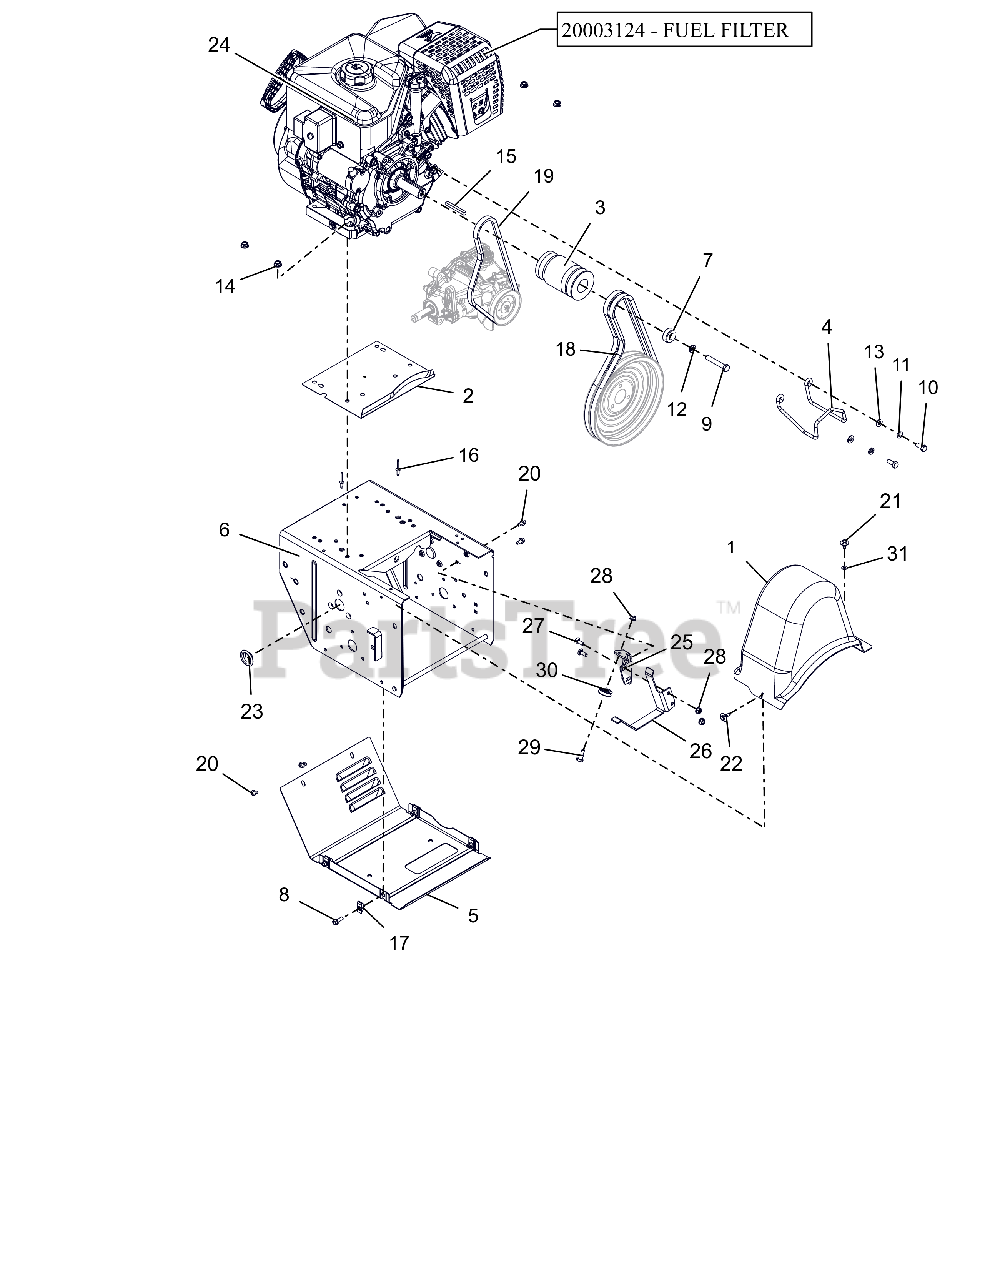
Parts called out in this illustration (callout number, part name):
1	COVER, BELT-LARGE
2	BAFFLE, WATER - LARGE BLOCK
3	SHEAVE, COMBO HYDRO WHEEL 4L
4	FINGER, BELT
5	COVER, BOTTOM - VENTILATED
6	FRAME, MAIN - PRO (WELDMENT)
7	BSHG-SPACER .47X1.25X.50
8	BLT-HEX .25-20X.75 HWH YZ GR5
9	BLT-HEX .38-24X2.25 YWZC GR5
10	BLT-HEX .31-24X.75 YWZC GR5
11	WSHR-LK .312X.097 HVY YWZC
12	@WSHR-LK .38X.094 REG YWZC
13	@WSHR-FL-STL.344X.688X.065YWZC
14	@NUT-LK-CTR-FLG .31-18 YZ GR F
15	KEY .25X.25X2.25
16	RVT-POP .187 YZ
17	NUT-RTNR .25-20X.56
18	V-BELT, HA-RAW EDGE (SET)
19	V-BELT, 4L-WRAPPED
20	SCR-TAP .25-20X.50 HWH TR YWZ
21	SCR-TAP .25-20X.50 LGHWH TR YZ
22	SCR-TAP .25-20X.5 CAPTIVE
23	PLUG, HOLE - 1.125"
24	ENGINE, EFI 420 GEN 3 240V/60W
24	FILTER, FUEL - IN-LINE EFI
25	BRACKET, CLUTCH CABLE
26	FINGER, BELT - FLAT
27	@BLT-RDHDSQNK .25-20X.75 G5YZ
28	@NUT-LK-TOP-FLG .25-20 YWZC
29	BOLT, SHLDR-.375X.375X.25-20
30	PULLEY, CABLE
31	NUT-PUSH .25X.50 O.D.
